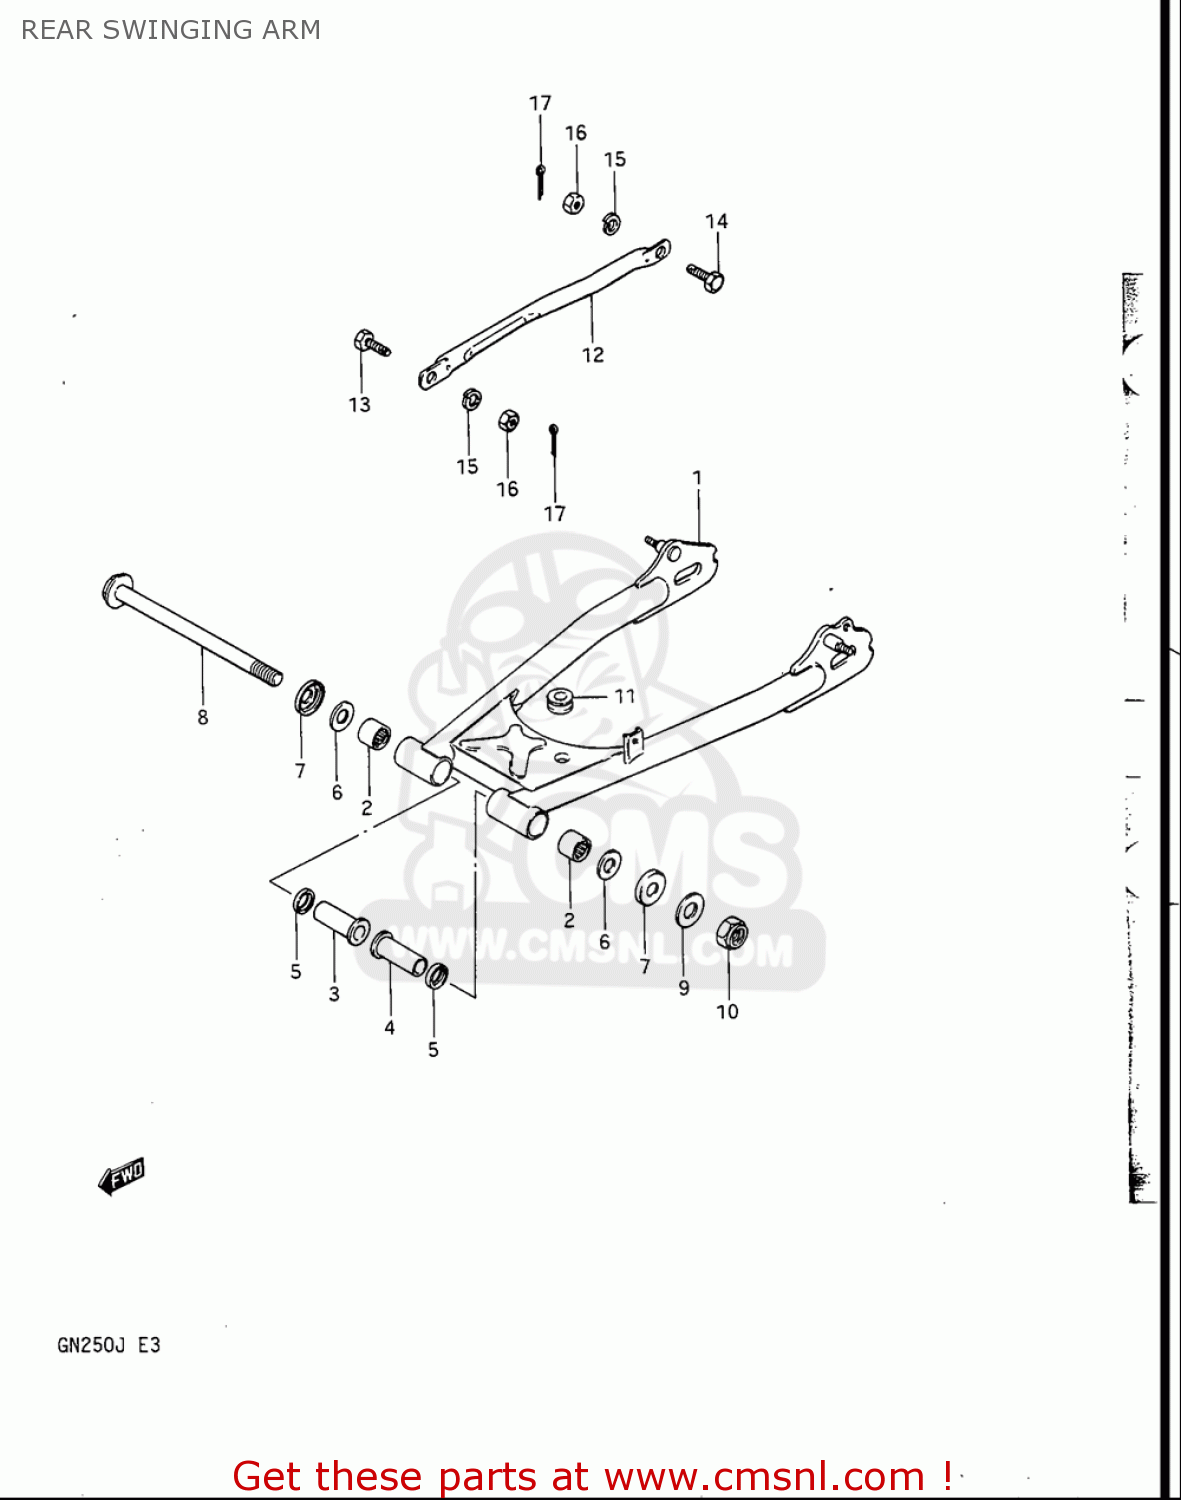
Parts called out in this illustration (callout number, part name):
1	SWINGINGARM ASSY,RR
2	BEARING(20X27X20)
5	SEAL,OIL(20X27X5)
8	SHAFT,RR SWINGINGARM PIVOT
9	WASHER
10	NUT 14MM
11	CUSHION
13	BOLT(8X22.5)
14	BOLT(8X26.5)
15	WASHER,LOCK
16	NUT
17	PIN
